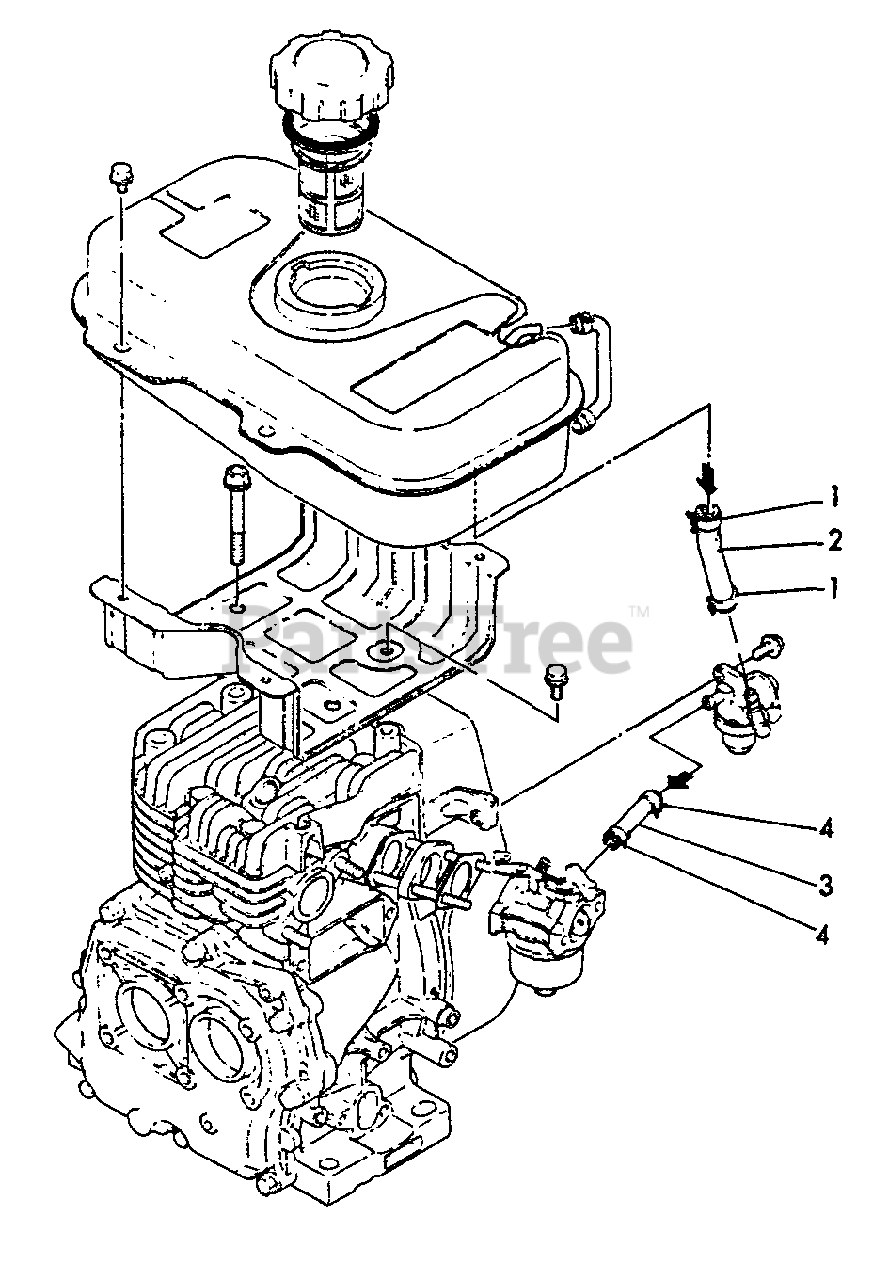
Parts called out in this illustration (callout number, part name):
1	CLAMP, HOSE
2	PIPE - FUEL -- A
3	PIPE - FUEL
4	CLAMP
